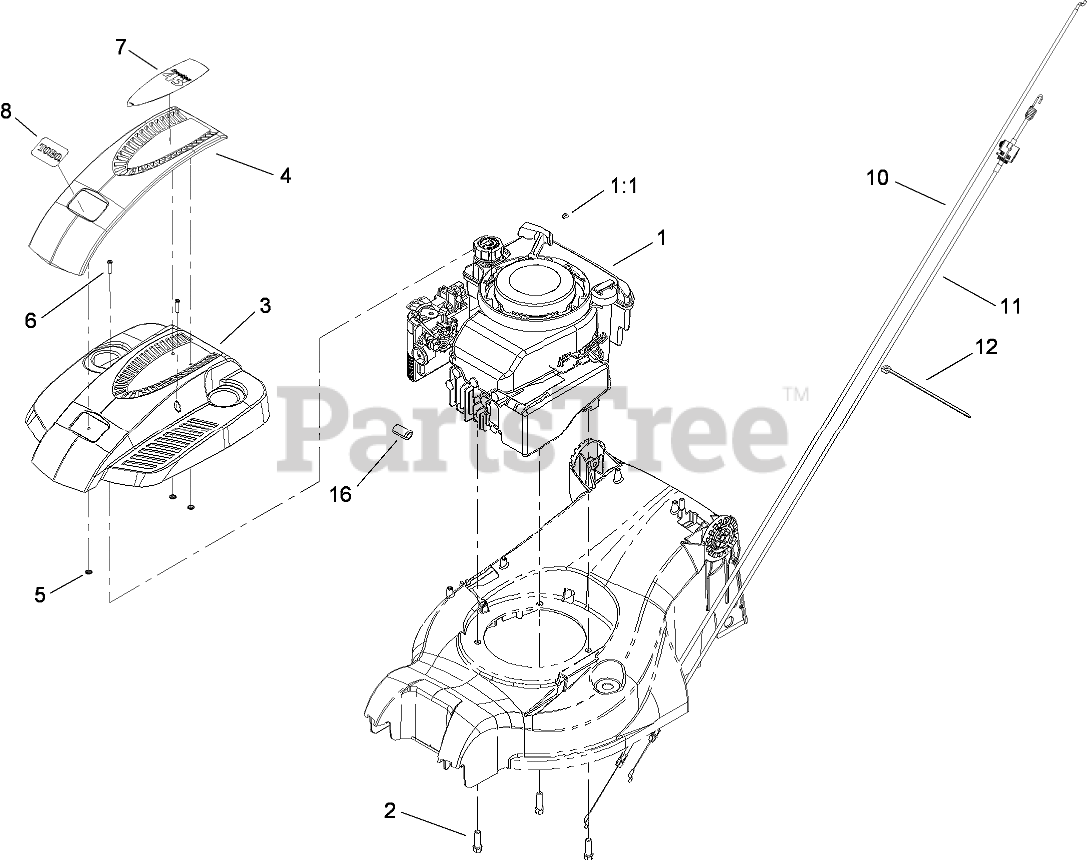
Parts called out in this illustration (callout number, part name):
1:1	STOP-ROPE
2	SCREW-TAPTITE
3	SHROUD-ENGINE
4	COVER-SHROUD
5	CLIP-PUSH
6	SCREW-PPH
10	CABLE-BRAKE
11	CABLE-TRACTION
12	TIE-CABLE
16	FERRITE-SNAP ON
